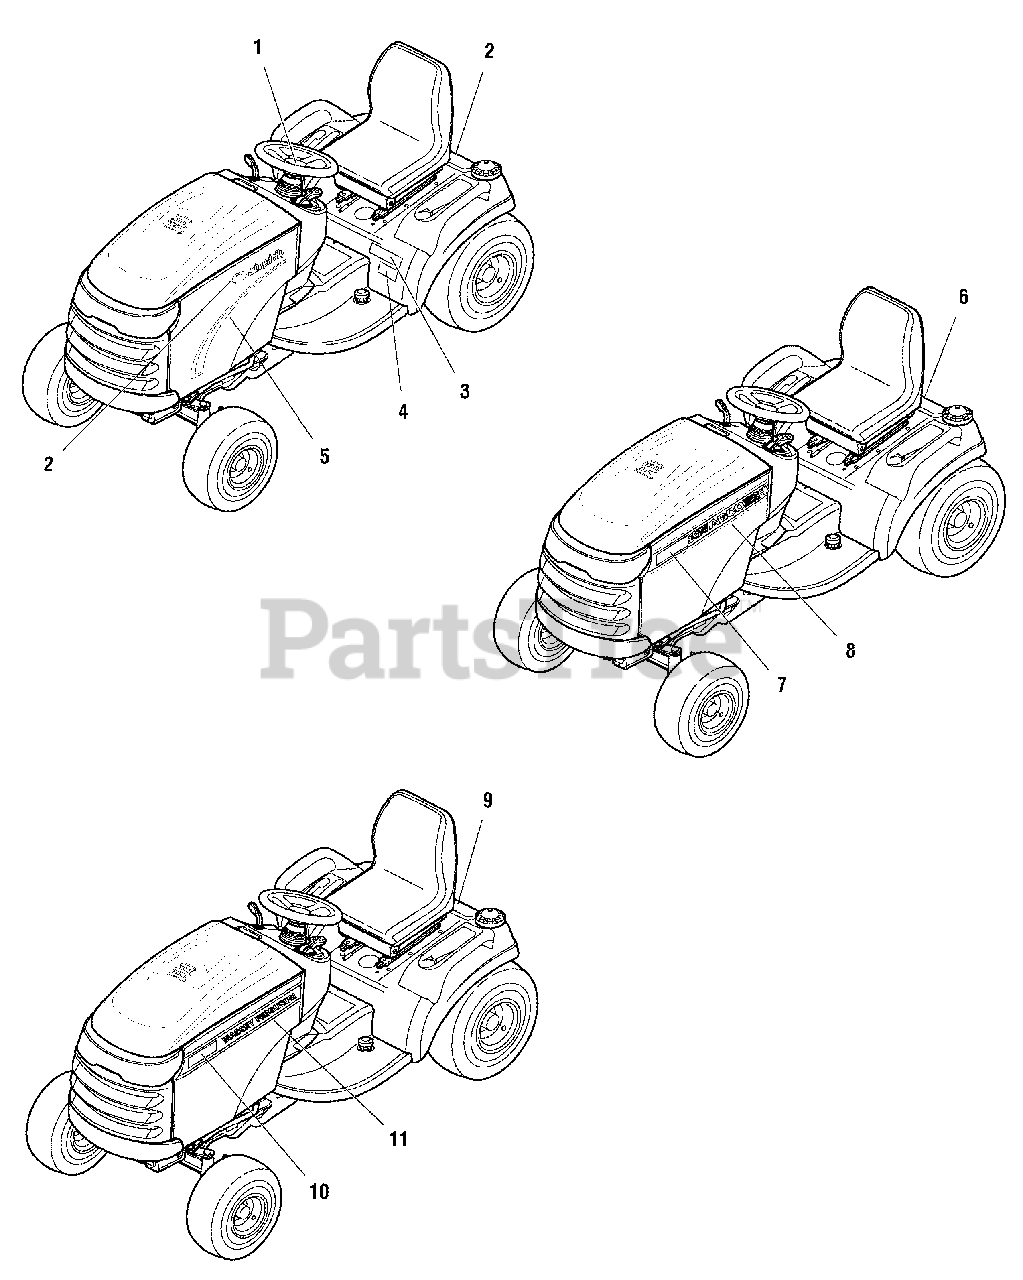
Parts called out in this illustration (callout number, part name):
1	DECAL, SMI Steering Wheel Icon Orange
2	DECAL, Simplicity Silver & Blue w/Icon
3	DECAL, Prestige, Silver & Blue
4	DECAL, 25HP Silver on Clear
4	DECAL, 27HP Silver on Clear
5	DECAL, Hood Stripe R.H. SMI Blue & Silver
5	DECAL, Hood Stripe L.H. SMI Blue & Silver
6	DECAL, AGCO, Logo
7	DECAL, 1825, AGCO White/Clear
7	DECAL, 1827, AGCO White/Clear
8	DECAL, Hood Stripe L.H. AGCO
8	DECAL, Hood Stripe R.H. AGCO
9	DECAL, Massey Ferguson Logo
10	DECAL, 2825, Massey
10	DECAL, 2827, Massey
10	DECAL, 2830, Massey
11	DECAL, Hood Stripe L.H. Massey
11	DECAL, Hood Stripe R.H. Massey
